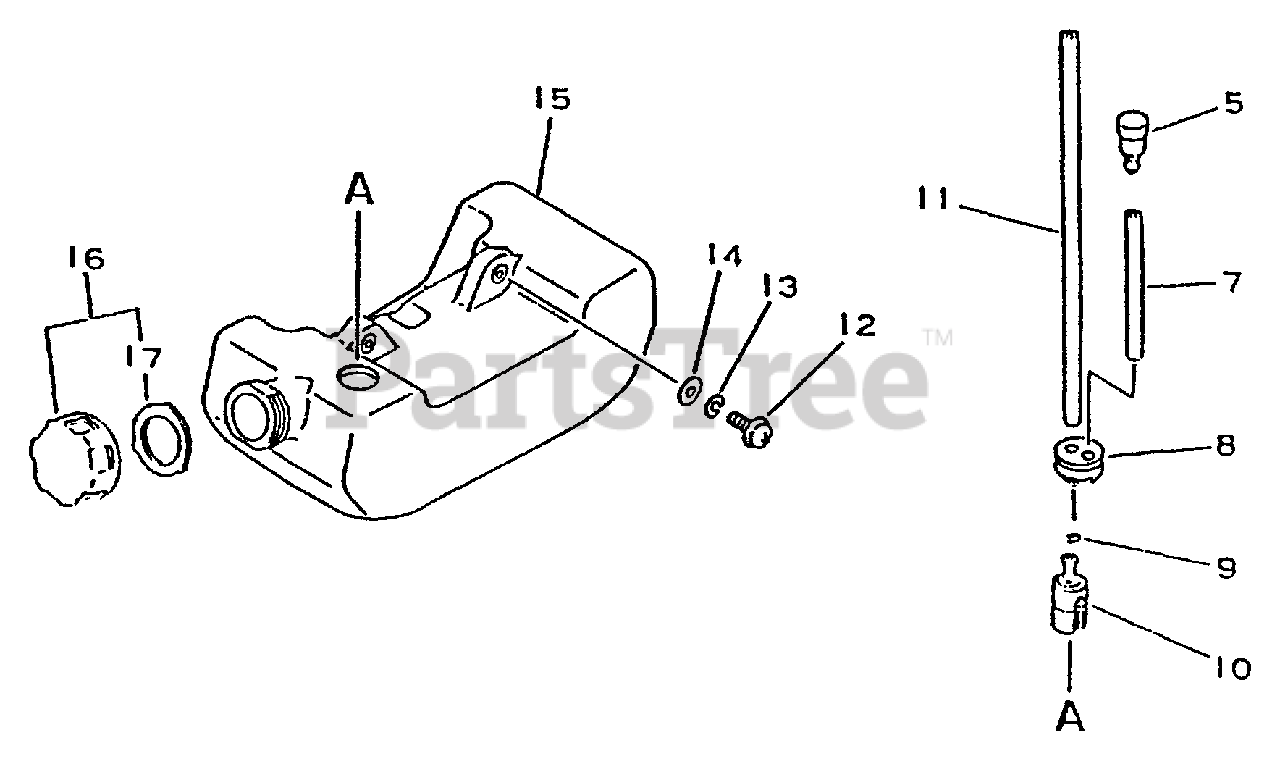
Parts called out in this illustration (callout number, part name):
5	Vent Assembly
7	Pipe
8	Grommet
10	Strainer, Fuel
11	Pipe, Fuel
12	Screw 5=16
13	Washer, Spring 5
14	Washer 5
15	Tank, Fuel
16	Cap Ass'y, Fuel Tank
17	Gasket, F, Tank Cap
